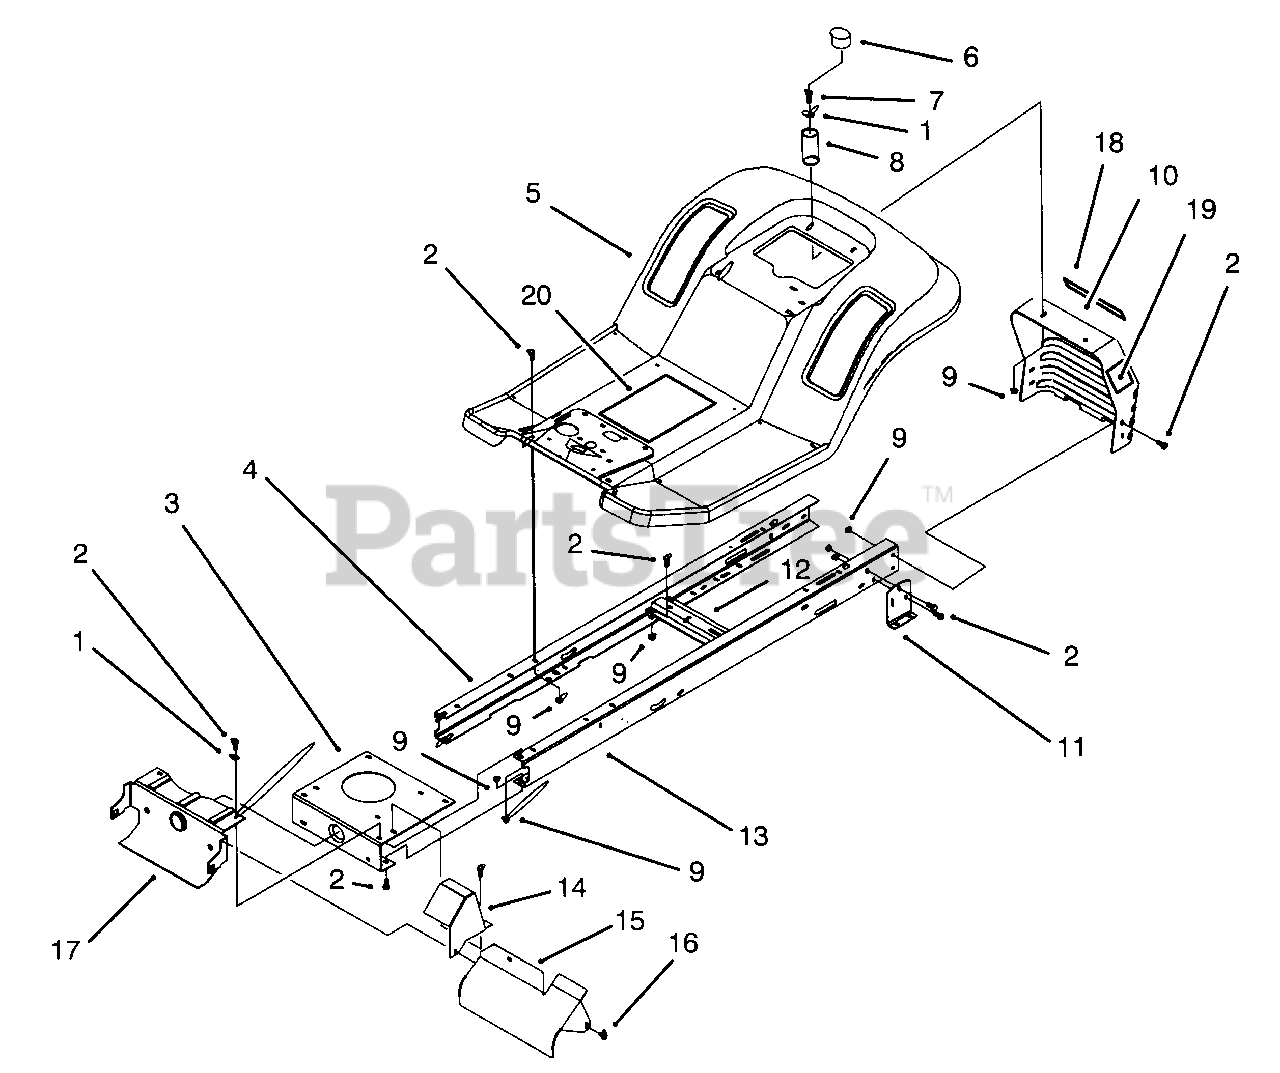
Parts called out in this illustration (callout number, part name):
1	Washer-Flat
2	Screw-Hex Hd. Cap
3	Plate-Engine Mount
4	Rail-R.H. Frame
6	Cap-Protector
7	Screw-Hex Hd. Cap
8	Spring-Compression
9	Nut-Lock
10	Panel-Rear Hitch
11	Bracket-Transaxle Mnt.
12	Bracket-Idler Pivot
13	Rail-L.H. Frame
14	Shield-Exhaust Pipe
15	Shield-Muffler
16	Screw-Thread Tapping
17	Support-Front Axle
18	Decal-Rear Body
19	Decal-Dump Valve Hydro (Model No. 81181 Only)
20	Decal-Instruction (Model No. 81140 & 81180 Only)
